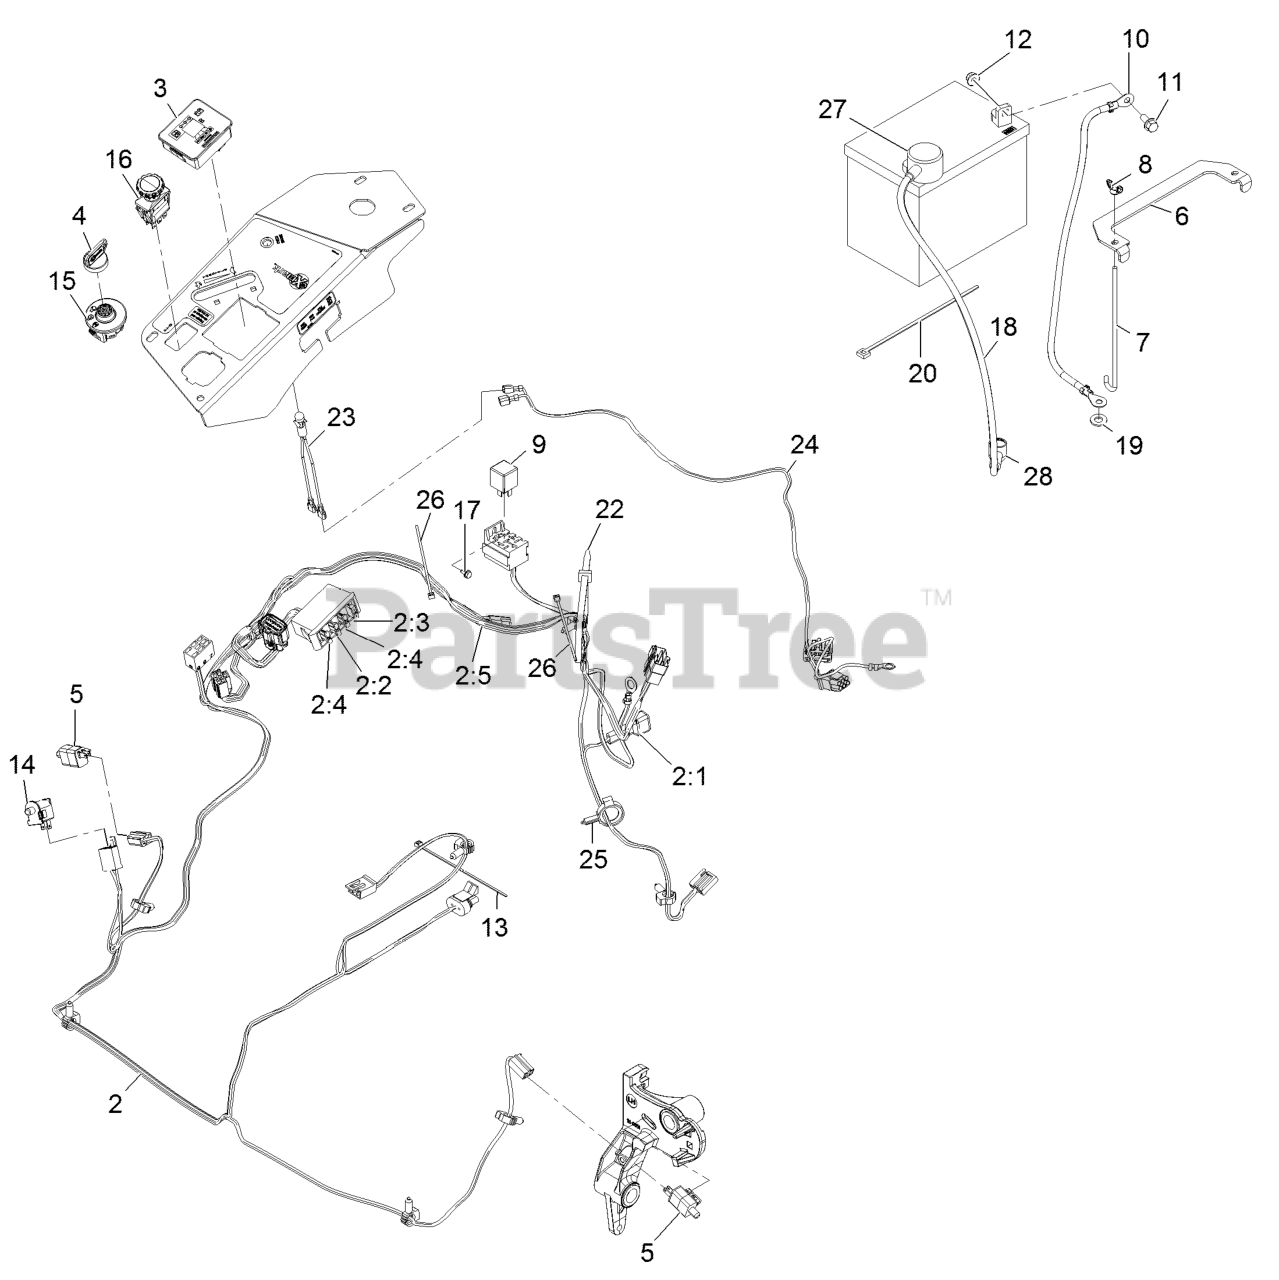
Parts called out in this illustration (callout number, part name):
2	HARNESS-WIRE, MAIN
2:2	FUSE-BLADE, 10 AMP
2:3	FUSE-BLADE, 15 AMP
2:4	FUSE-BLADE, 25 AMP
2:5	CAP-PLUG
3	FUEL/HOUR METER ASM
4	KEYS-IGNITION (SPARE PAIR
4	KEY-IGNITION
6	STRAP-TIE DOWN, BATTERY
7	BOLT-HOLDDOWN
8	WINGNUT
10	CABLE-BATTERY, NEGATIVE
11	SCREW-HHF
12	NUT-HF, NI
13	TIE-CABLE
14	SWITCH-BAIL
16	SWITCH-PTO, 10 AMP
17	SCREW-HWH
18	CABLE-BATTERY, POSITIVE
19	WASHER-FLAT
20	TIE-PLASTIC
22	TIE-PLASTIC
23	INDICATOR-LED, RED
24	HARNESS-LIGHT, INDICATOR
25	CLAMP-HOSE
26	TIE-CABLE
27	INSULATOR-BATTERY
28	INSULATOR-SOLENOID
